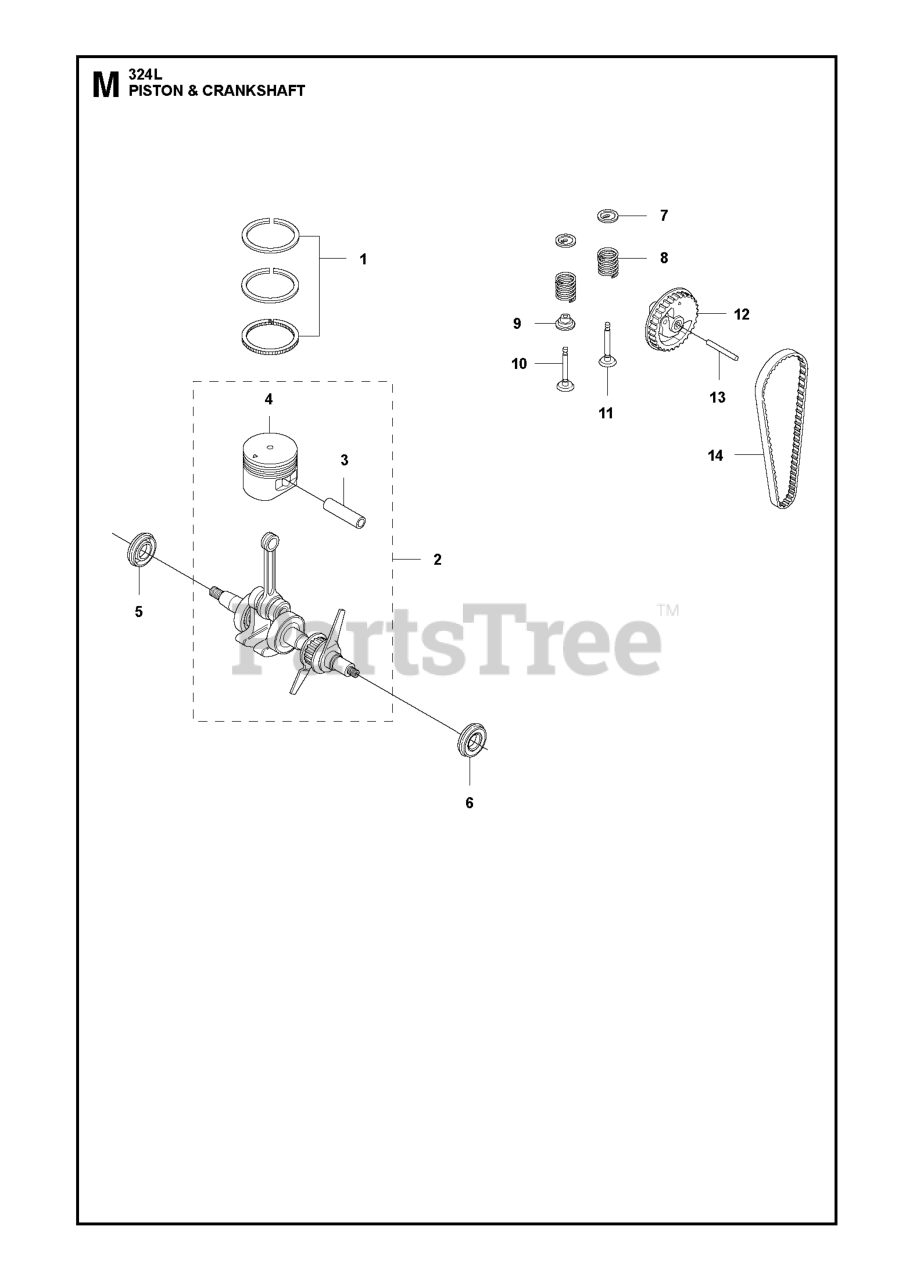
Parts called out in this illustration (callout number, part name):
1	PISTON RING
2	CRANKSHAFT
3	PISTON BOLT
5	SEALING RING
6	SEALING RING
